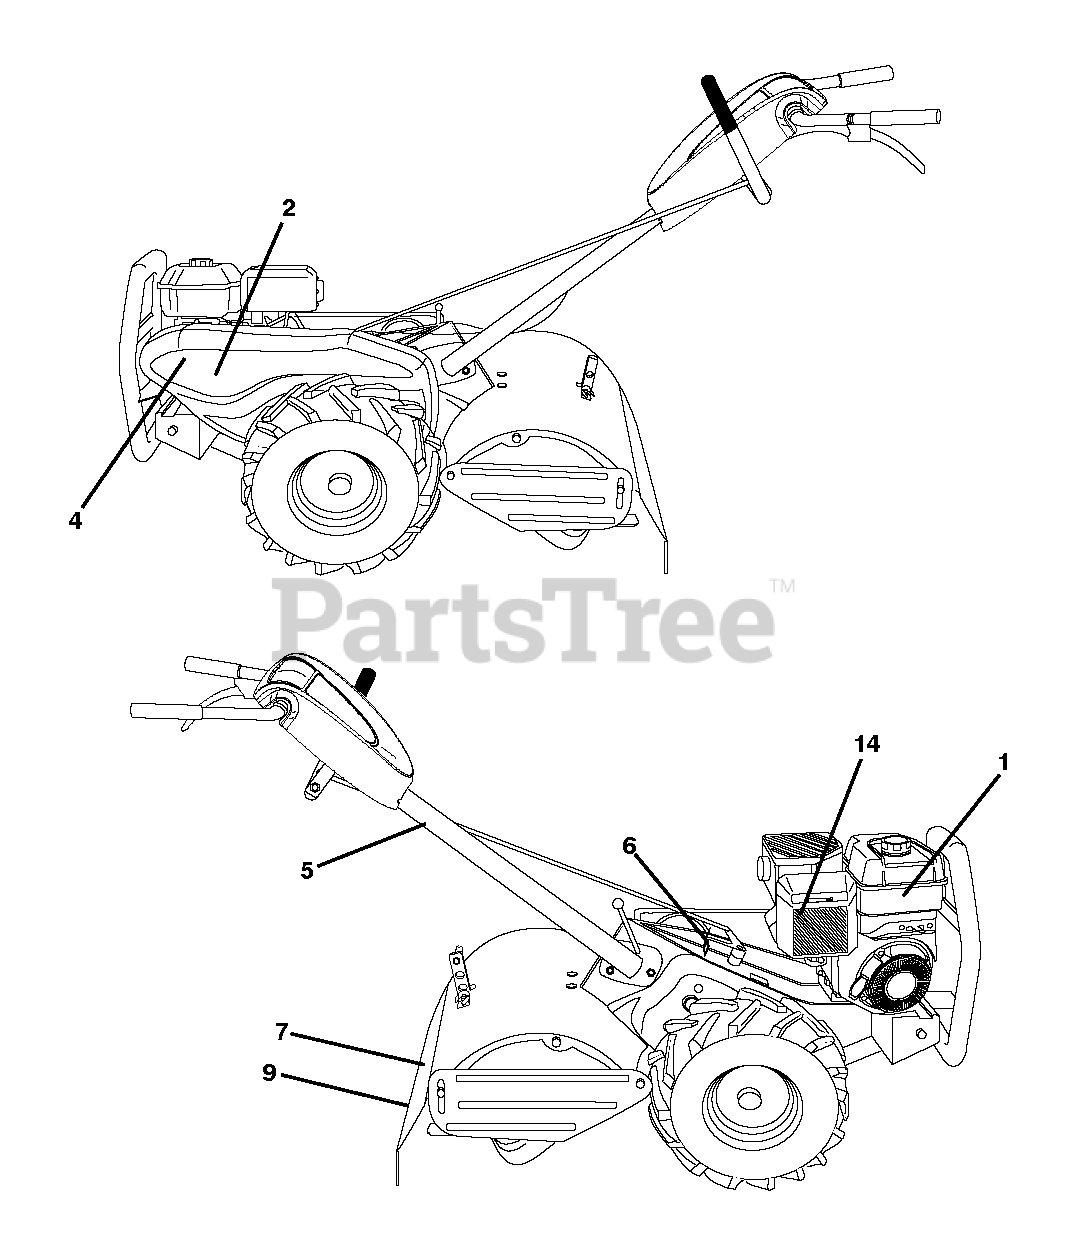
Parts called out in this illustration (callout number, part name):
1	Decal, B&S 900 TANK REF 276991
5	DECAL TI
6	DECAL.SHIFT.INDICATOR.TILLER
7	DECAL WARNING
14	DECAL.B&S.900.A/S.C
